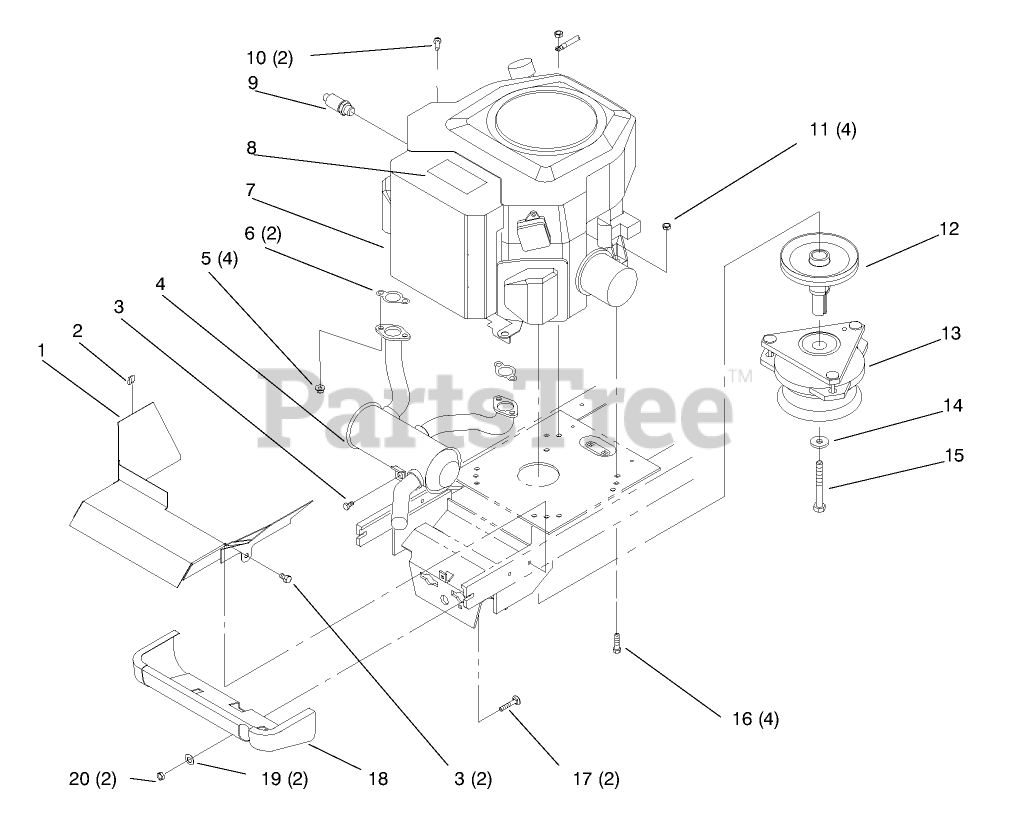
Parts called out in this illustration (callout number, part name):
2	CLIP-RETAINER, WIRE
3	SCREW-HWHTF
4	MUFFLER - TWIN
7	ENGINE - KOHLER 20
8	Decal-Toro Power Plus 19
9	VALVE-DRAIN, OIL
10	SCREW-PPH
11	NUT-LOCK, NI
12	PULLEY-ENGINE
13	CLUTCH - PTO
14	WASHER
15	SCREW-HH
16	SCREW-HH
17	BOLT-CARR
19	WASHER-FLAT
20	NUT-LOCK, NI
